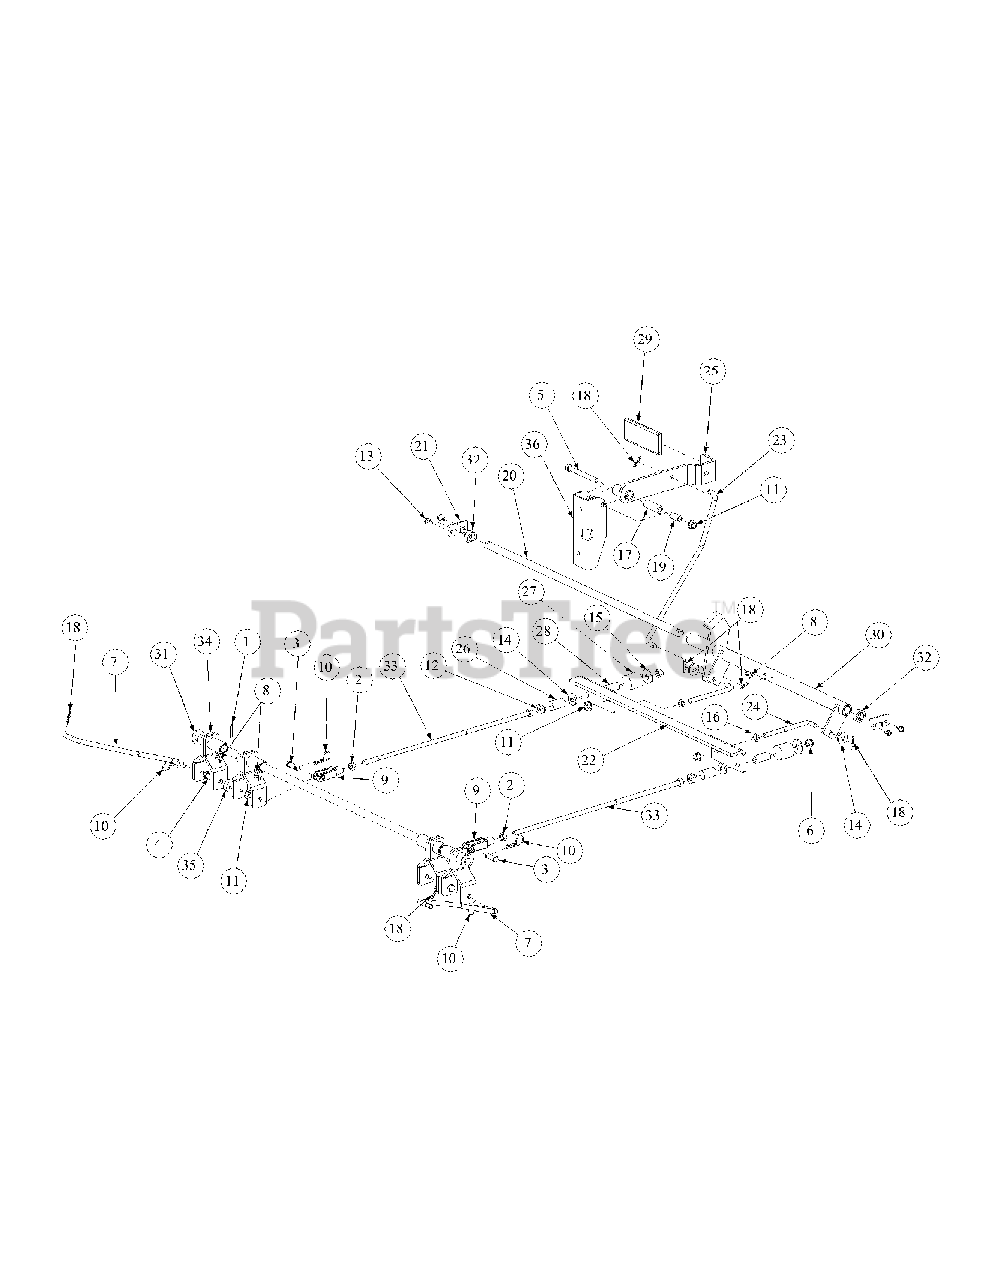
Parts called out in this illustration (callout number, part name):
1	Cotter Pin, .125 x 1.0
2	Hex Nut, 3/8-16
3	Clevis Pin, 3/8 x 1-1/8
4	Hex Cap Screw, 3/8-16 x 1.50
5	Hex Cap Screw, 3/8-16 x 3-1/2
5	Hex Cap Screw, 3/8-16 x 3-1/4
6	Nylock Nut, 3/8-16
7	Linkage Brake Rod
8	Grease Fitting, 1/4 -28, 90 degree
9	Yoke, 3/8-16
10	Hair Pin, 3/8" - 1/2"
11	Flange Lock Hex Nut, 3/8-16
12	Shoulder Nut
13	Screw, 1/4-20 x 1-1/2
14	Flat Washer, .406 ID x 1.0 OD x .105
15	Flat Washer, .411 x 1.25 x .100
16	Jam Nut, 3/8-16
17	Spacer, .39 x .63 x 1.75
18	Cotter Pin, .072 x 1.12 Lg
19	Spacer, .375 x .50 x 1.02 Lg
20	Bellecrank Mounting Shaft
21	Parking Brake Shaft Holder
22	Brake Bracket
23	Brake Rod
24	Connector Rod, 3/8 OD x 5.75
25	Brake Handle
26	Neutral Brake Spring
27	Force Brake Spring
28	Center Brake Hose
29	Parking Brake Grip
30	Brake Bearing Hub
31	Flat Washer, 5/8
32	Shaft Collar, .625 ID x 1" OD x .438
33	Connector Rod, 3/8 OD x 17.88 Lg
34	Rear Brake Arm Assembly
35	Spacer, .406 x 1.00 x .38
36	Park Brake Mounting Bracket
